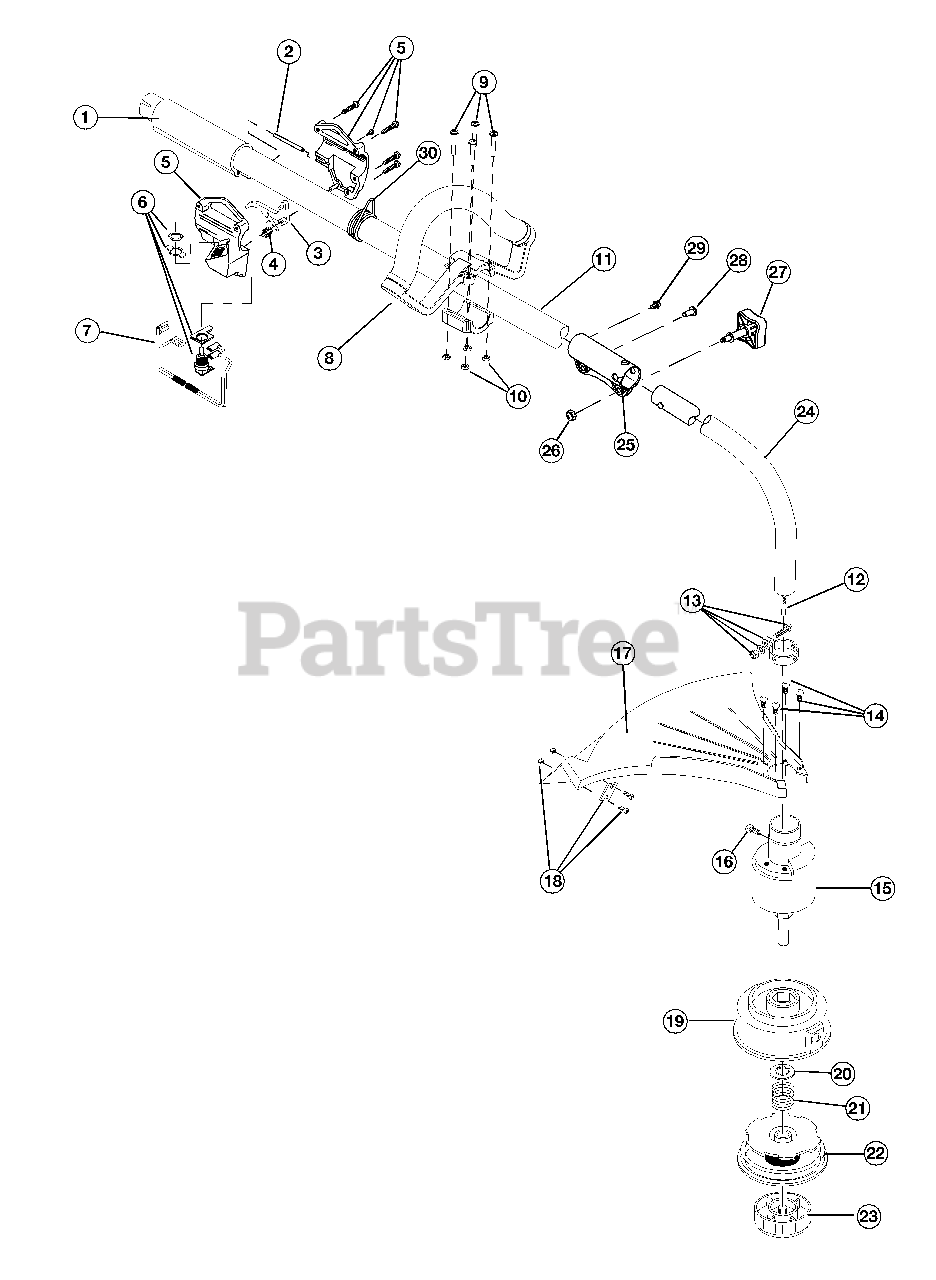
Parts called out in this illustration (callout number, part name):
2	Throttle Cable Assembly
3	Throttle Trigger
4	Throttle Trigger Spring
5	Throttle Trigger Assembly (includes 3 & 4)
6	Switch Assembly
7	Wire Lead Assembly
8	Loop Handle Assembly
10	Nut
11	Upper Drive Shaft Hsg Assembly
12	Lower Flex Shaft
13	Lower Clamp Assembly
14	Shield Mounting Screw
15	Bushing Housing Assembly w/shaft
15	Bushing Housing w/o shaft
16	Anti-Rotation Screw
17	Shield Assembly (includes 18)
18	Blade Assembly
19	Outer Spool Assembly (includes 20)
21	Spring
22	Inner Reel
23	Bumb Knob Assembly
24	Lower Drive Shaft Hsg
25	Split Boom Coupler Assembly (includes 26-29)
27	Knob (includes 26)
30	Harness Clip
